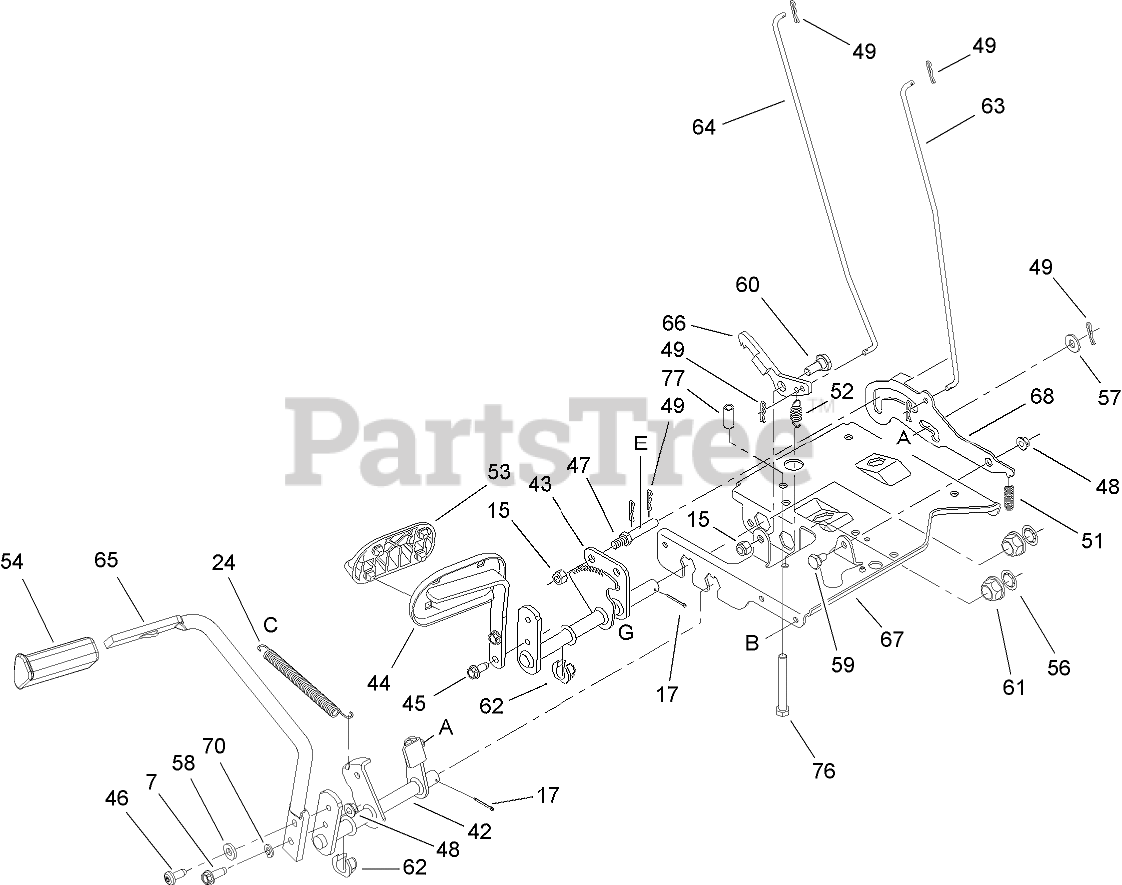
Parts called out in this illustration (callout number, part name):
7	SCREW-HWHTF
15	NUT-LOCK, FLANGE
17	PIN-COTTER
24	SPRING-EXTENSION
42	BRAKE CONTROL ASM
43	SPEED CONTROL ASM
44	PEDAL ASM
45	SCREW-HWH
46	SCREW-TAP
48	NUT-LOCK, FLANGE
49	PIN-COTTER
51	SPRING
52	SPRING-EXTENSION
53	PAD-PEDAL
54	PAD-BRAKE
56	WASHER-FLAT
57	Washer-Flat
58	WASHER-FLAT
59	BRACKET-TORQUE
60	BOLT-SHOULDER
61	BEARING-FLANGE
62	BEARING-FLANGE, HEX (SPLIT)
63	ROD-BRAKE, LOCK CONTROL
64	ROD-CONTROL, CRUISE
65	PEDAL-BRAKE
66	LATCH-CRUISE
67	BRACKET-SUPPORT, STEERING
68	BRACKET-LOCKOUT
70	WASHER-LOCK
76	SCREW-HH
77	SPACER
